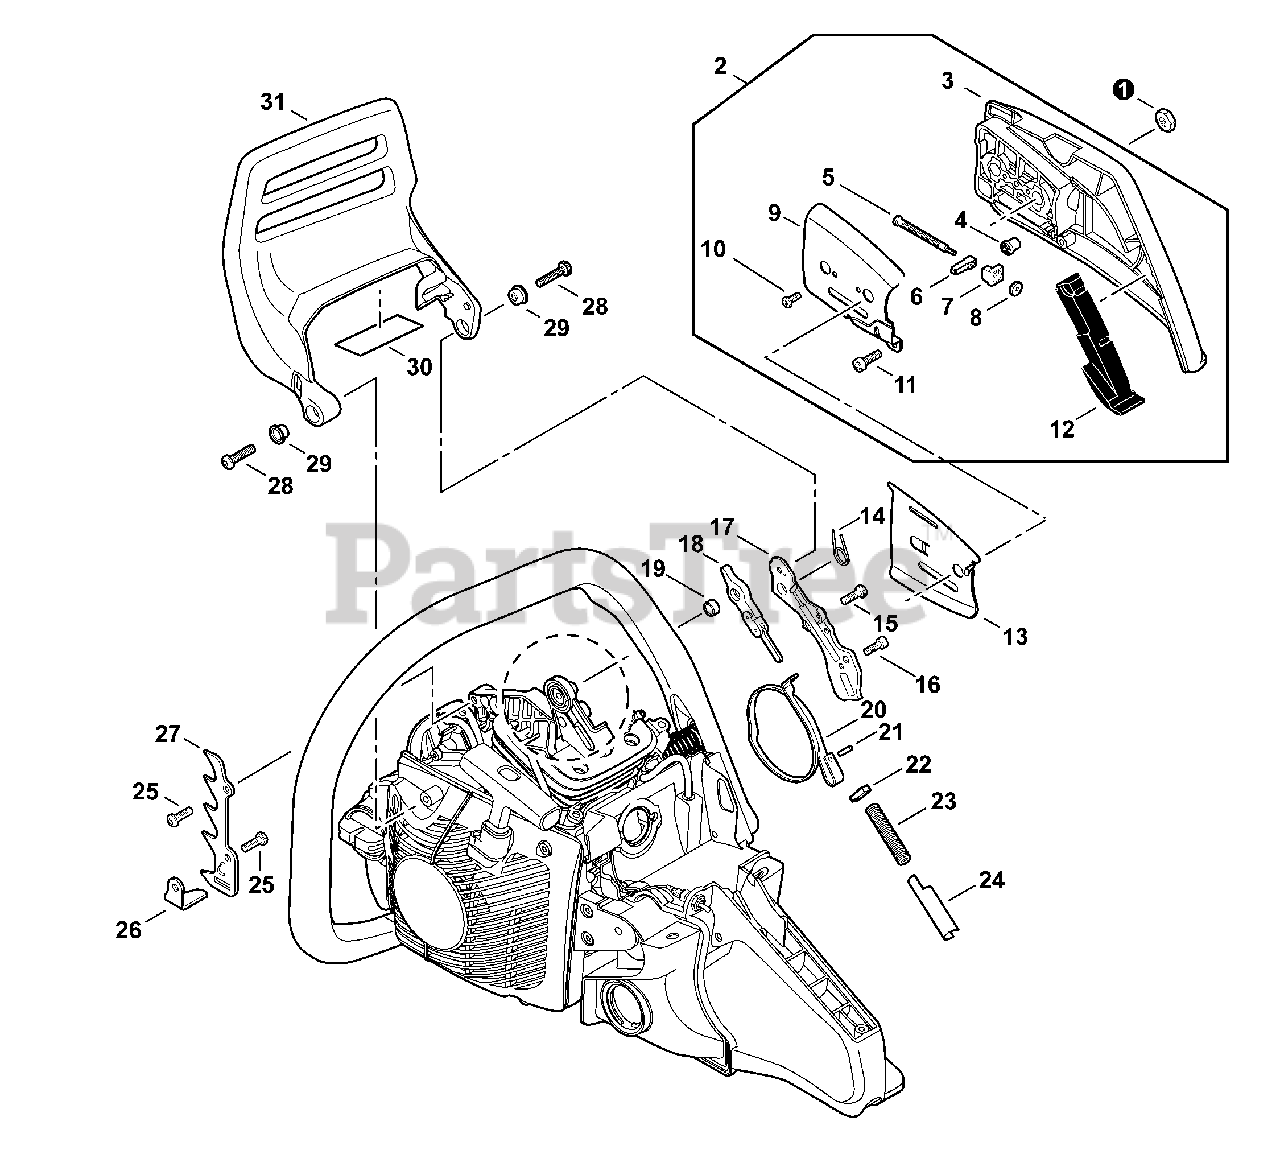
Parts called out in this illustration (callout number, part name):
1	NUT, FLANGE M8×1.25
2	GUARD KIT, SPROCKET
3	GUARD, SPROCKET
4	GEAR, BEVEL
5	SCREW, CHAIN TENSION 63 MM
6	TENSIONER, CHAIN
7	COLLAR 8
8	GEAR, BEVEL
9	PLATE, GUIDE - OUTER
10	SCREW 3×6
11	BOLT, TORX 4×12
12	CUSHION
13	PLATE, GUIDE - INNER
14	SPRING, TORSION
15	BOLT, TORX 5×16
16	BOLT, TORX 4×12
17	COVER, BRAKE
18	CONNECTOR, BRAKE
19	SPACER 12×10×T: 1.0
20	BAND, BRAKE
21	PIN, SPRING 3x-9.8
23	SPRING, COMPRESSION Ø12×70.5
24	PLATE, SIDE
25	BOLT, TORX 5×16
26	CHAIN CATCHER
27	SPIKE, BUMPER
28	BOLT, TORX 5×16
29	COLLAR 11.2×16.2×T0.6
30	SHIELD, HEAT 75×27×0.15
31	LEVER, BRAKE
